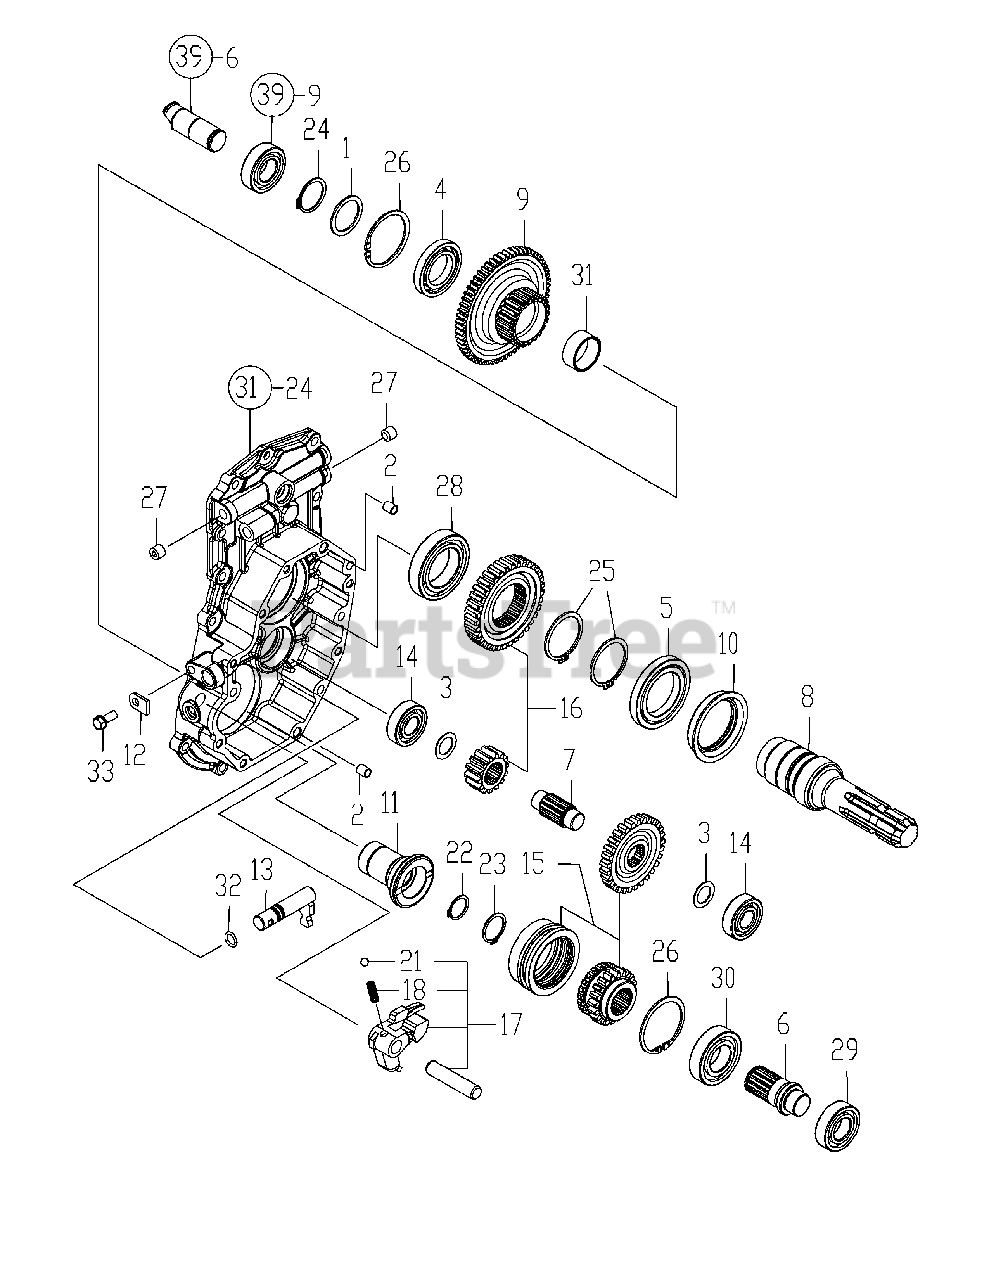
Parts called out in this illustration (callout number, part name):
1	SPACER,CLUTCH SHAFT
2	COLLAR, 8X10X11.5
4	BEARING, 16007
5	BEARING, 16010
6	SHAFT, REAR PTO
7	SHAFT, REAR PTO IDLE
8	REAR PTO SHAFT
9	GEAR, PTO Z=62 B
10	SEAL, TCFY557214
11	COLLAR, SPLINE
13	SHAFT, MBR CHANGE
14	BEARING, 6204RSH2
15	GEAR KIT, 20-29
16	GEAR KIT, 14-35
28	BEARING, 6009 NTN
29	BEARING, 6205 NTN
30	BEARING, 6206 NTN
31	NEEDLE, 354017
32	PACKING, P 12.5
